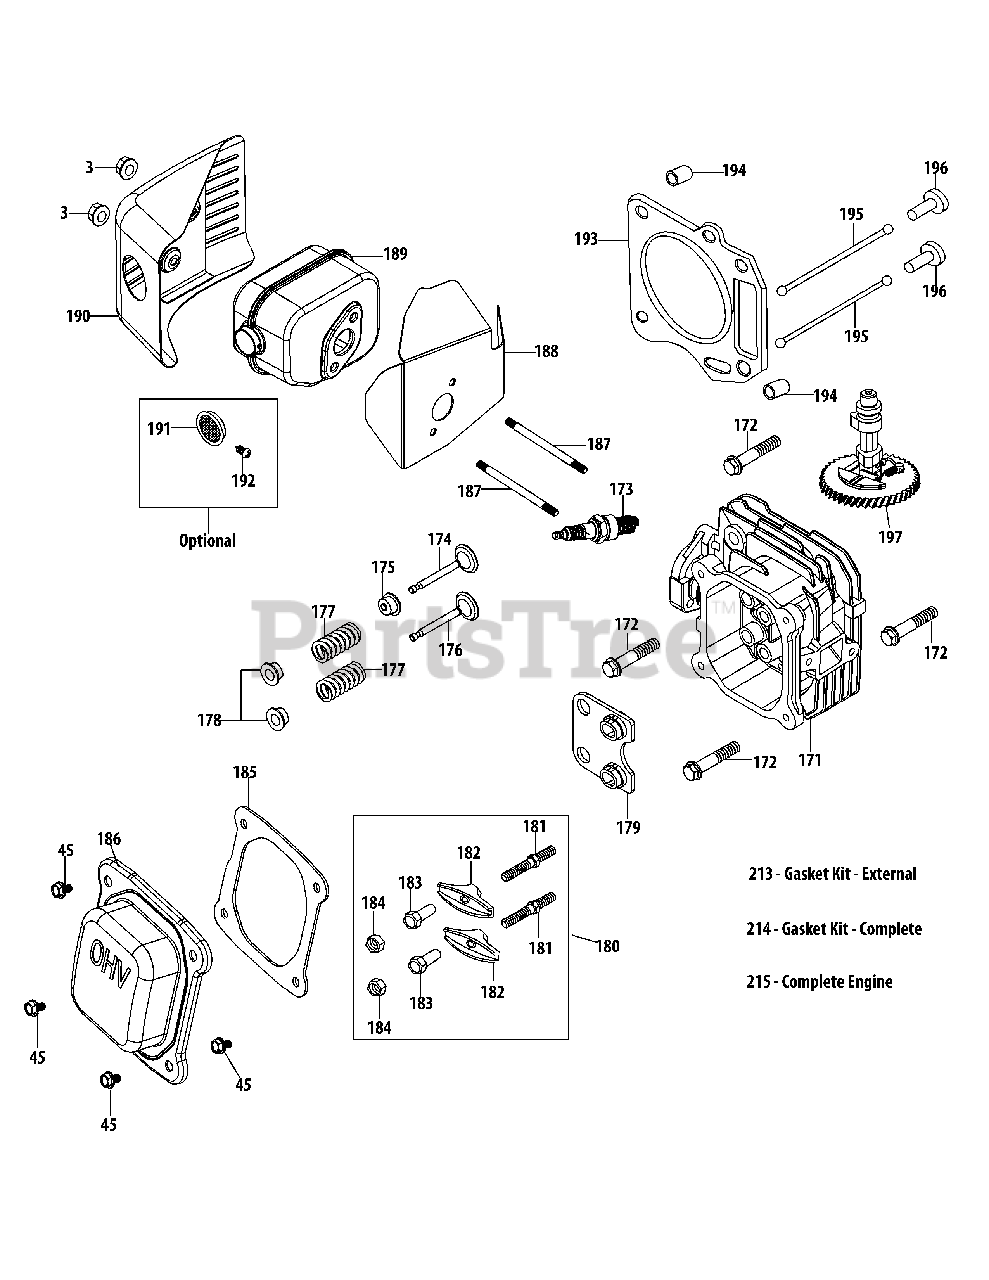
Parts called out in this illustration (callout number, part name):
3	Nut M6X10Mm
45	Bolt M6×14
171	Cylinder Head Service Kit
171	Cylinder Head Assembly
172	Bolt M8X54 Cylinder Head
173	Spark Plug
175	Intake Valve Seal
177	Valve Spring
178	Valve Spring Retainer
179	Push Rod Guide
180	Rocker Arm Assembly
181	Rocker Arm Stud
182	Rocker Arm
183	Fulcrum Nut
185	Valve Cover Gasket
186	Valve Cover
187	Muffler Stud M6X95
187	Muffler Stud Assemlby
188	Muffler Gasket
189	Muffler Assembly
190	Muffler Shield
191	Spark Arrestor
192	Spark Arrestor Screw
193	Cylinder Head Gasket
194	Cylinder Head Dowel Pin 10×16
195	Push Rod Kit
197	Camshaft Assembly
213	Gasket Kit - External
214	Gasket Kit - Complete
215	Complete Engine
